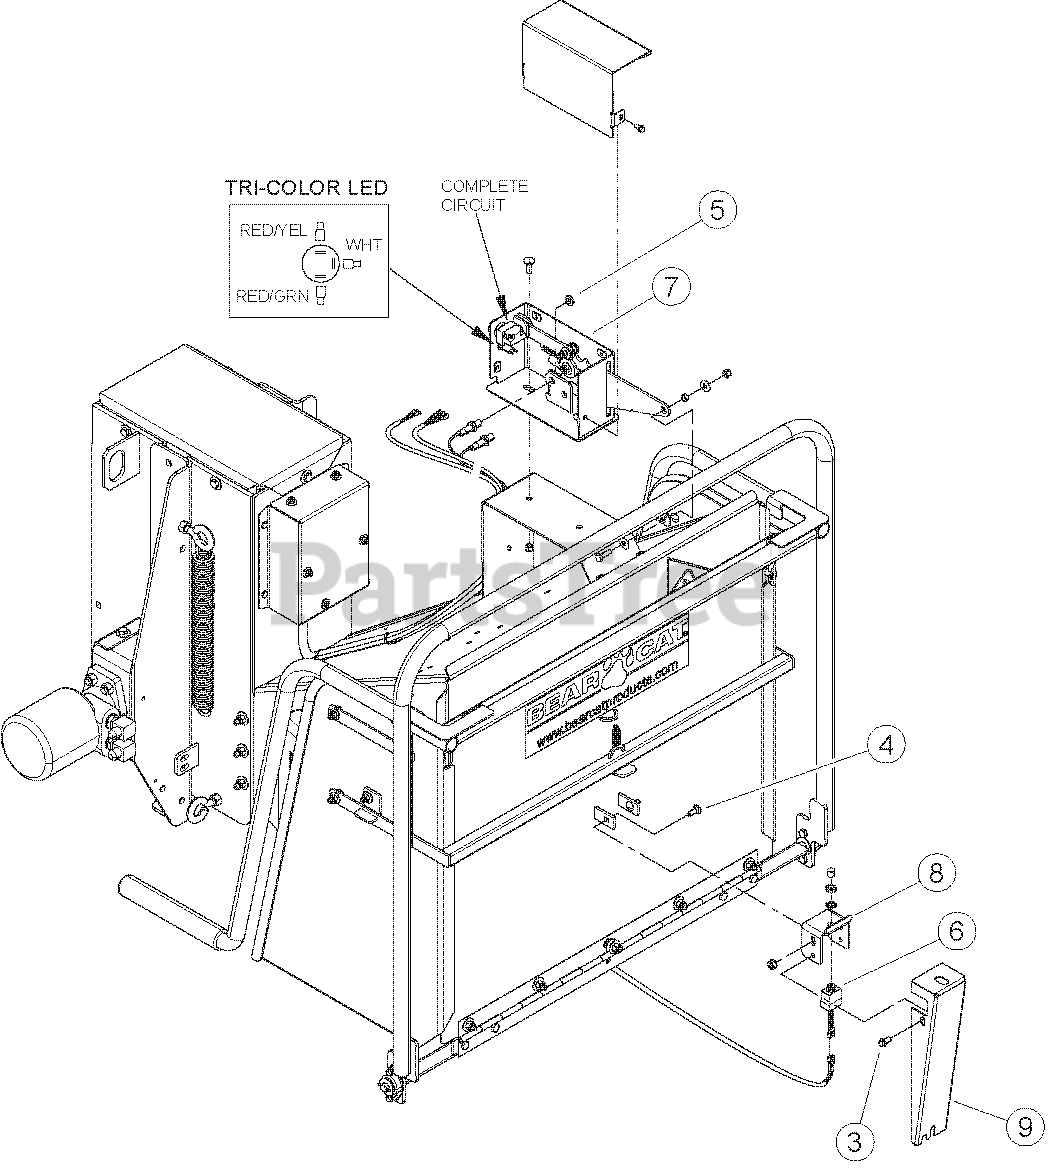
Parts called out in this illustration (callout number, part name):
1	CONNECTOR, 1/4 QD FEMALE (NOT PICTURED)
2	CONNECTOR, 1/4 QD MALE (NOT PICTURED)
3	SCW,11/32*7/8 HWH AB THREAD ZP
4	BOLT,CARR 5/16*7/8" GR5 NC ZP
5	NUT, 5/16-18 NYLOCK-FLANGE
6	SWITCH, MOMENTARY IP67 NORMALLY ON
7	ASSEMBLY, SWITCH BOX
8	BRACKET, SWITCH
9	SHIELD, SAFETYBAR SWITCH
